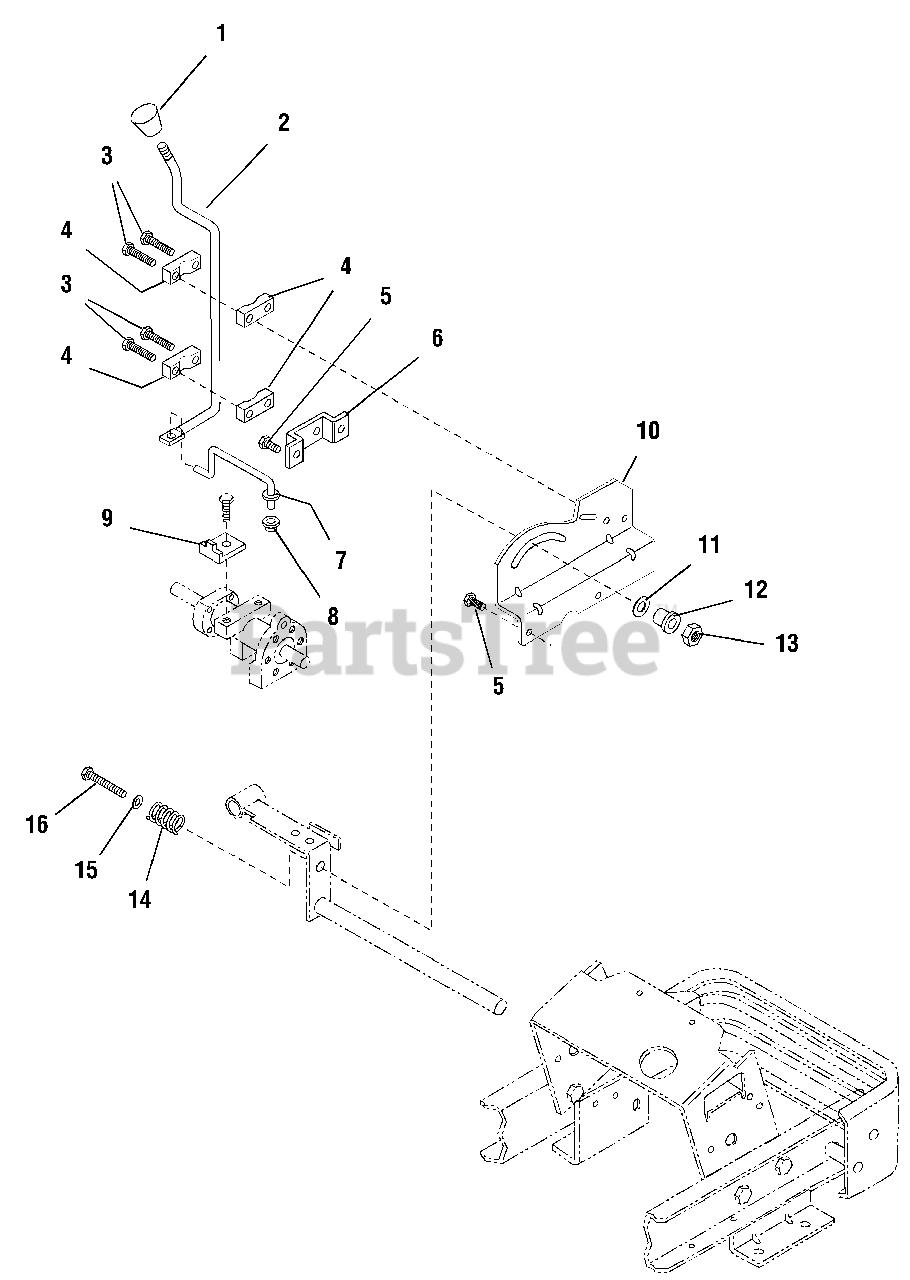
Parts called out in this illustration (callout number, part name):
1	KNOB, Two Speed
2	ROD, Two Speed
3	CAPSCREW, Hex Hd, Taptite, 5/16-18 x 1-1/2
4	BEARING HALF, Nylon
5	CAPSCREW, Hex Hd, Taptite, 5/16-18 x 3/4
6	BRACKET, Two Speed
7	ROD, Two Speed, Lower
8	NUT, Push
9	QUADRANT, Two Speed
10	BRACKET, Slotted
11	WASHER, 1/2 x 1-1/4
13	NUT, Hex, Nylon Lock, 5/16-18
14	SPRING, Compression
15	WASHER, Flat, 5/16
16	CAPSCREW, 5/16-18 x 2-1/2
